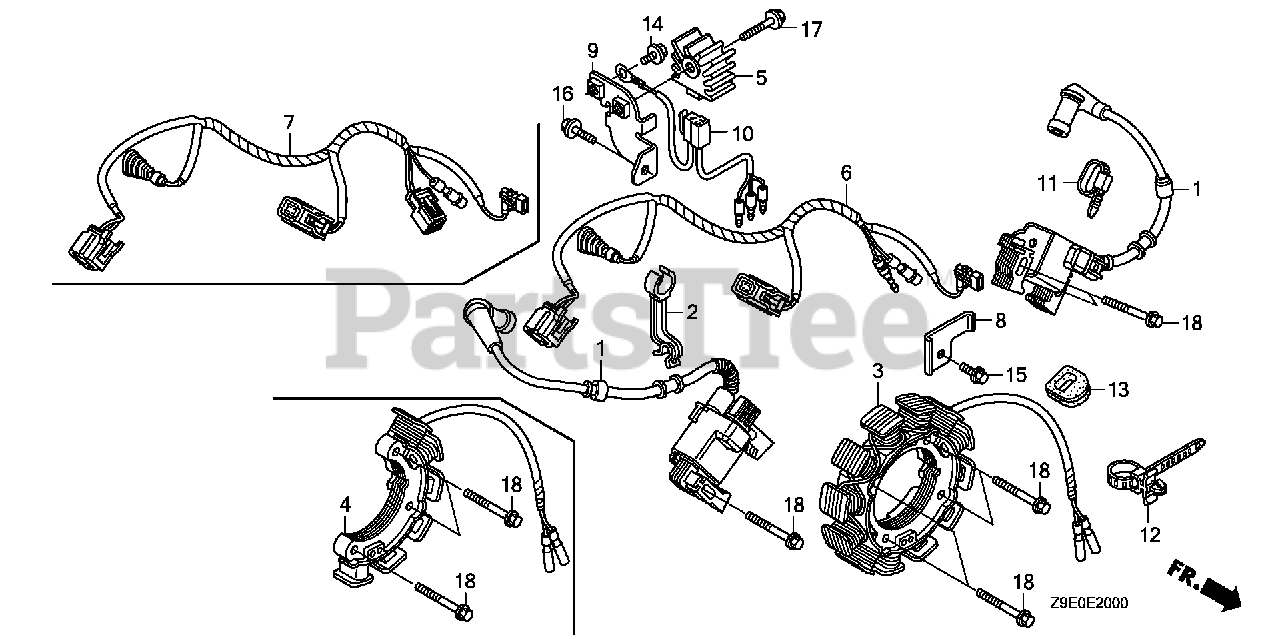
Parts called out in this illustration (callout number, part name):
1	COIL ASSY., IGNITION
2	CLAMP, IGNITION WIRE
4	COIL ASSY., CHARGE (2.7A)
5	RECTIFIER, REGULATOR (5A)
7	WIRE HARNESS ASSY., ENGINE
8	BRACKET, HARNESS
9	BRACKET, REGULATOR RECTIFIER
10	HARNESS ASSY., REGULATOR RECTIFIER
11	BAND, WIRE (95MM)
12	STRAP, CABLE (105MM) (BLACK)
13	GROMMET, CORD
14	BOLT, FLANGE (6X8)
15	BOLT, FLANGE (6X12)
16	BOLT, FLANGE (6X14)
17	BOLT, FLANGE (6X30)
18	BOLT, FLANGE (6X32)
